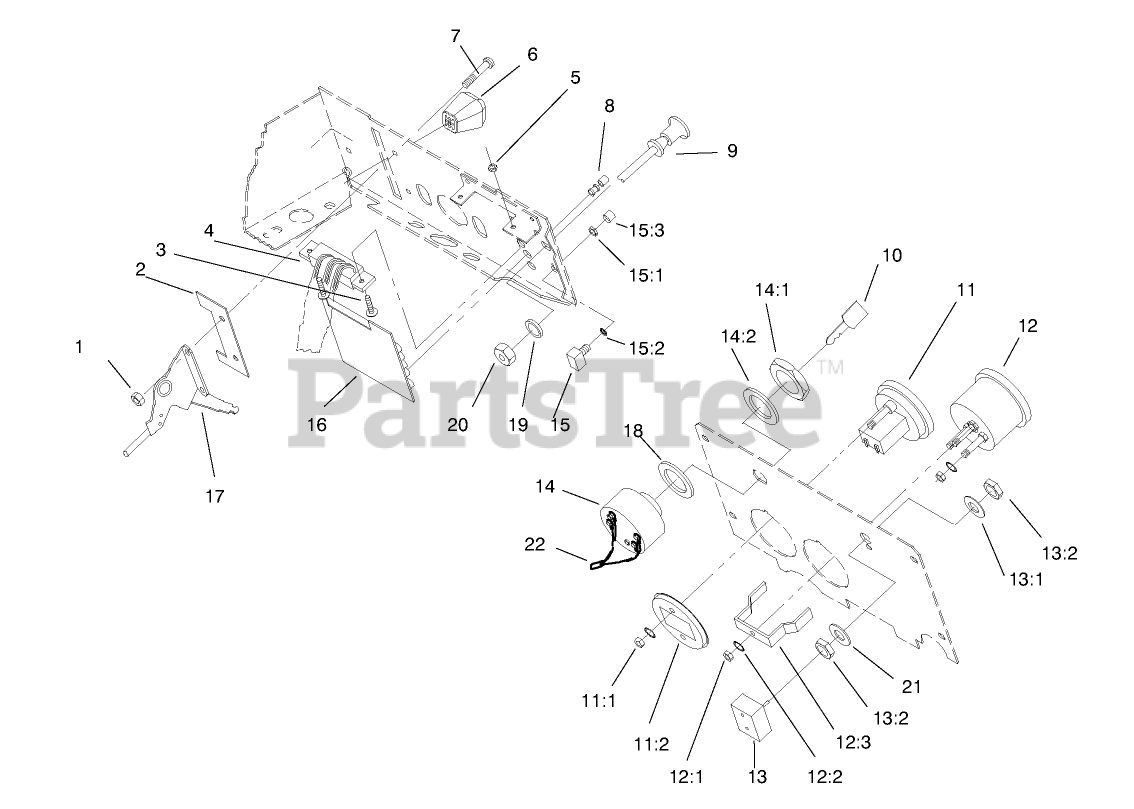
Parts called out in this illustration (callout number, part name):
3	Screw
4	P.C. BOARD HARNESS
5	NUT-HEX, NYL INS
7	SCREW-PPH
8	ASSY LENS & BUSHING
9	CONTROL-CHOKE
10	KEY-IGNITION
11:1	NUT-HEX, KEPS
11:2	Retainer
12	VOLTMETER
12:1	NUT-HEX
12:3	CLAMP-MOUNTING
13	SWITCH-LIGHTS
13:1	TAB-WASHER
13:2	*DISC**
14:2	WASHER-LOCK
15	SWITCH-PUSH BUTTON
15:1	NUT F/W 116796
17	CONTROL-THROTTLE
18	WASHER
19	WASHER-FLAT
20	NUT-HEX PALNUT
21	WASHER
22	WIRING-HARNESS & DIA
